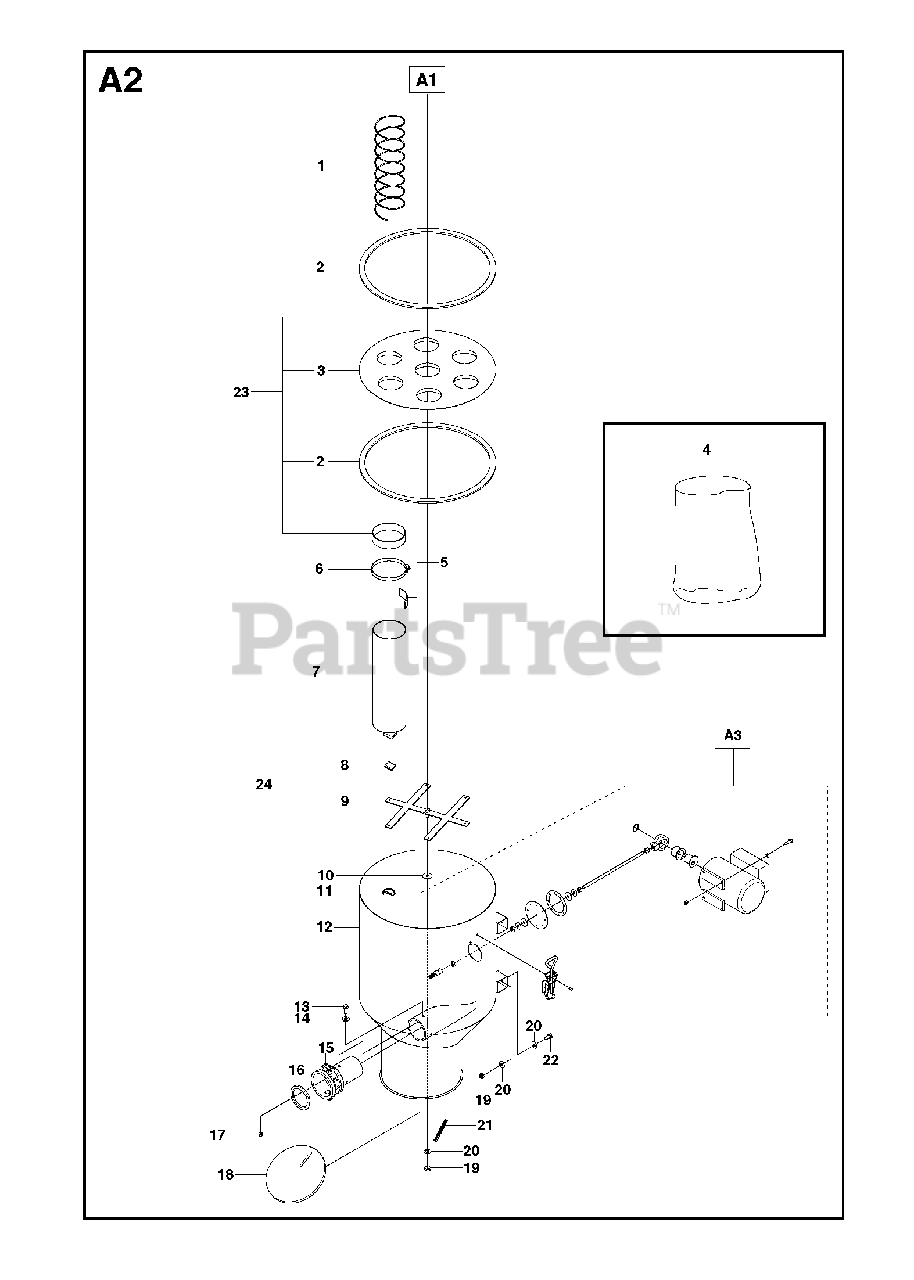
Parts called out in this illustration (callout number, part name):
14	WASHER
17	HEXAGON LOCKING NUT
19	HEXAGON LOCKING NUT
20	WASHER
